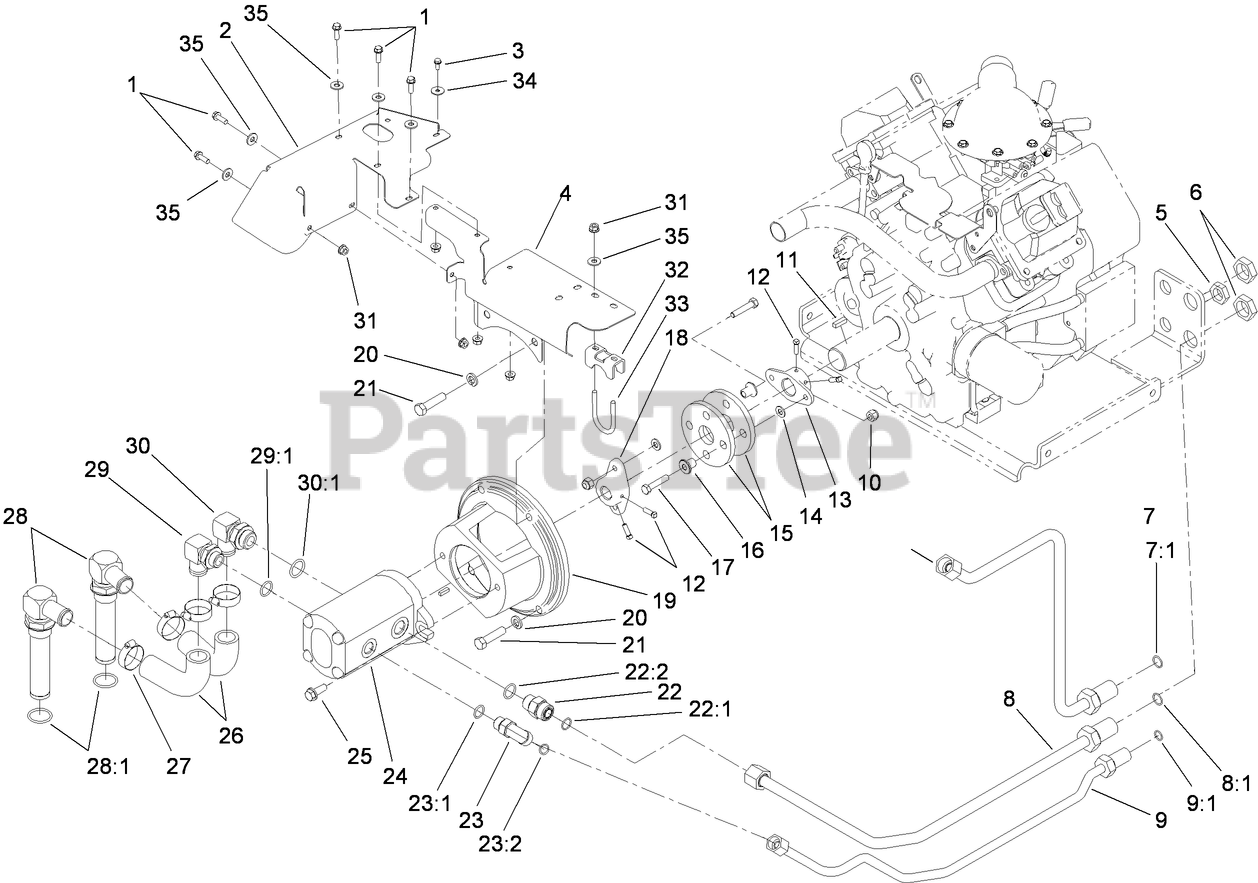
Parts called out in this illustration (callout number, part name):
1	SCREW-HWH
2	SHIELD-HEAT
3	SCREW-HWH
4	SHIELD-HEAT
5	NUT-BULKHEAD
6	NUT-LOCK, BULKHEAD
7	HYD TUBE ASM
7:1	O-RING
8	HYD TUBE ASM
8:1	O-RING
9	HYD TUBE ASM
9:1	O-RING
10	NUT-LOCK, NI
11	KEY-SQUARE
12	SCREW-SQH
13	HUB-ENGINE
14	WASHER-PLAIN
15	COUPLING-RUBBER
16	SPACER
17	SCREW-HH
18	HUB-PUMP
19	MOUNT-PUMP
20	WASHER-LOCK
21	SCREW-HH
22	FITTING-STRAIGHT
22:1	O-RING
22:2	O-RING
23	FITTING-ELBOW-90 DEG
23:1	O-RING
23:2	O-RING
24	HYD PUMP ASM
25	SCREW-HHF
26	HOSE-SUCTION, FORMED
27	CLAMP-HOSE
28	STRAINER FITTING ASM
28:1	O-RING
29	STEM-HOSE, 90 DEG
29:1	O-RING
30	FITTING-HYD, 90 DEG
30:1	O-RING
31	NUT-HHF
32	CLAMP-PIPE
33	U-BOLT
34	WASHER-FLAT
35	WASHER-FLAT
